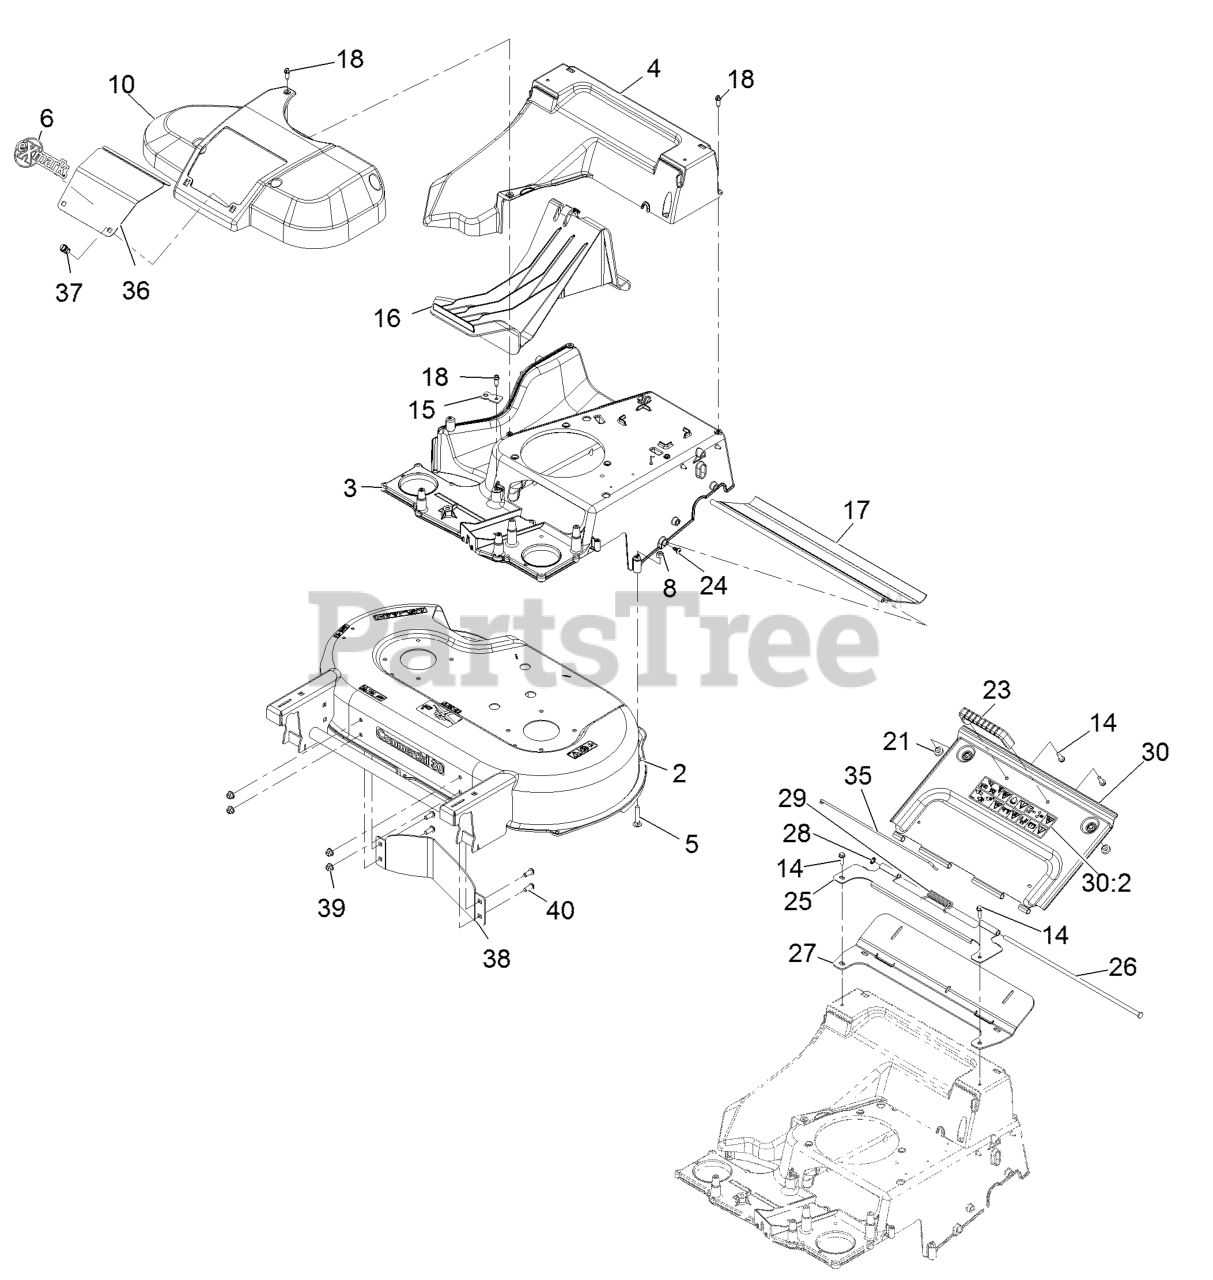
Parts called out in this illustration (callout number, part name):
5	SCREW-CARR
8	NUT-LOCK, NI
10	COVER-BELT
14	SCREW-HWH
16	PLUG-MULCH
17	SHIELD-TRAILING
18	SCREW-HWHTF
23	HANDLE-DOOR
24	SCREW-PTH
25	BRACKET-HINGE
26	PIN-HINGE
27	SEAL-DOOR
28	RING-RETAINING
29	SPRING-TORSION, COVER
30	REAR DOOR ASM
30:2	DECAL-WARNING
35	CLIP-SEAL
36	DOOR-ACCESS
37	FASTENER
38	BAFFLE-CONTROL
39	NUT-HF, NI
40	SCREW-HSBH
